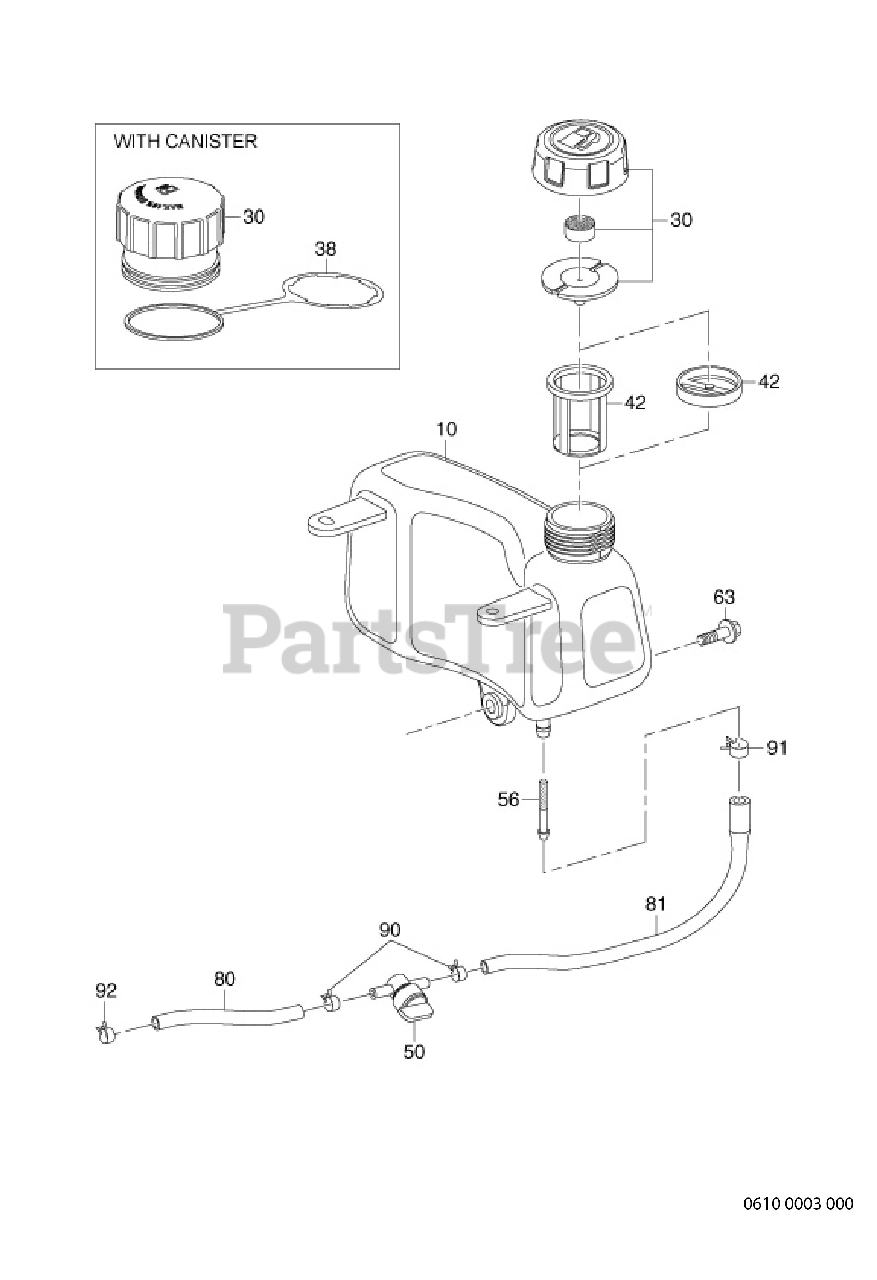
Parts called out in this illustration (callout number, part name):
10	FUEL TANK
38	TETHER (TANK CAP)
63	BOLT
81	FUEL HOSE
90	HOSE CLAMP
91	HOSE CLAMP
92	HOSE CLAMP
